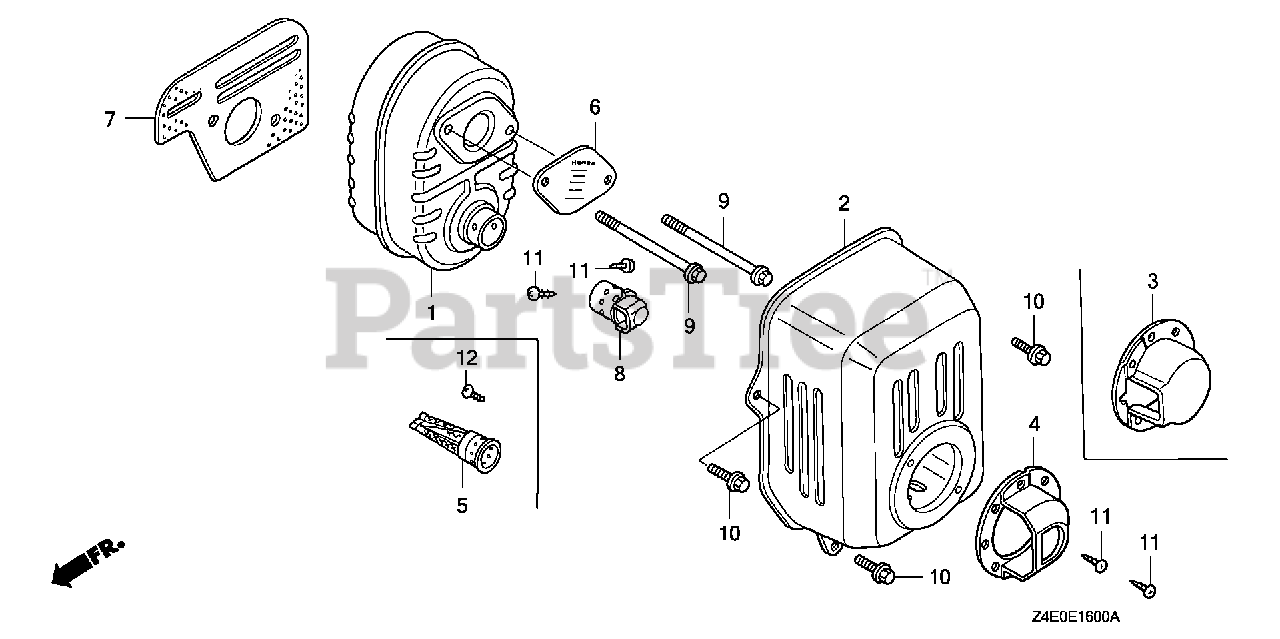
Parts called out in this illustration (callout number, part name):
2	PROTECTOR, MUFFLER
5	ARRESTER, SPARK (TO 1207644)
6	PLATE, ARRESTER NUMBER
7	GASKET, MUFFLER
9	BOLT, FLANGE (6X79) (CT200)
10	BOLT, FLANGE (6X14) (CT200)
12	SCREW, TAPPING (4X6)
